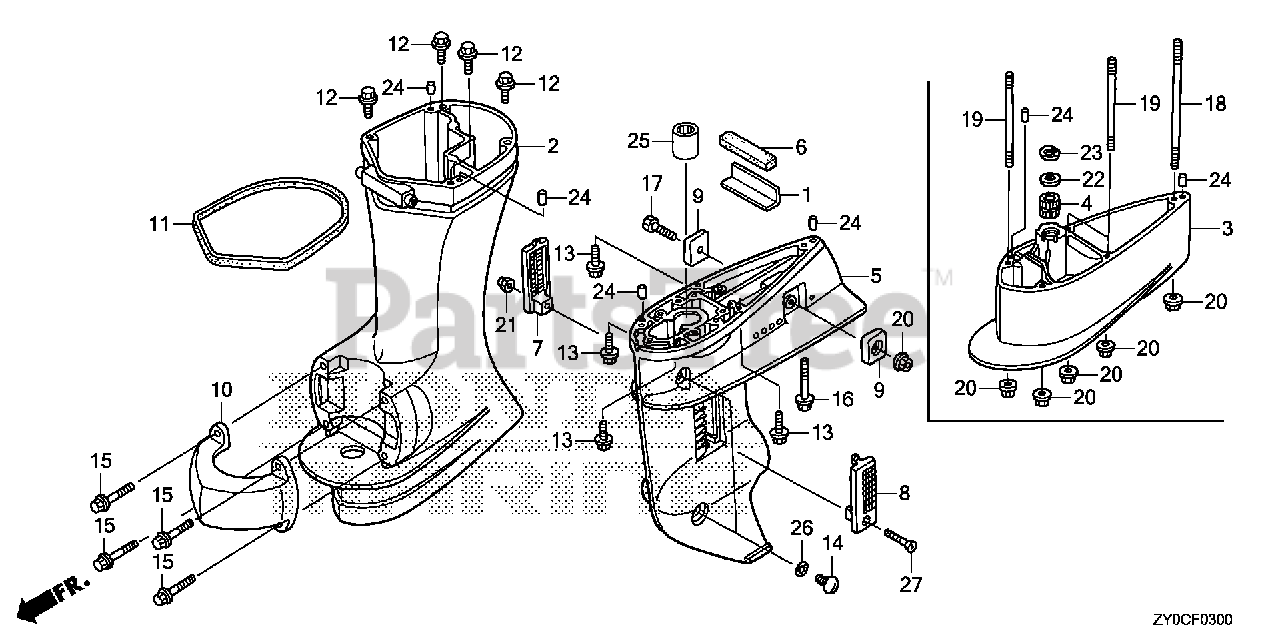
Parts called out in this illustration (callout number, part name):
1	PLATE, RUBBER SETTING
2	CASE, EXTENSION *NHB14M* (L) (AQUA MARINE SILVER METALLIC)
5	CASE, GEAR *NHB14M* (AQUA MARINE SILVER METALLIC)
6	GROMMET, GEAR CASE
7	SCREEN, R WATER
8	SCREEN, L. WATER
9	METAL, ANODE
10	HOUSING, MOUNTING (LOWER) *NHB14M* (AQUA MARINE SILVER METALLIC)
11	RUBBER, COVER (LOWER)
12	BOLT, FLANGE (8X35) Use from Frame SN 4800713.
13	BOLT, FLANGE (6X23) Use from Frame SN 4800343.
14	BOLT, OIL CHECK
15	BOLT, FLANGE (6X20) (ENGINE NO.)
16	BOLT, FLANGE (6X75)
17	BOLT, HEX. (6X25) Use up to Frame SN 4800342.
20	NUT, SELF-LOCK (6MM)
21	NUT, SELF-LOCK (5MM)
24	PIN, DOWEL (6X10)
25	BEARING, NEEDLE (15X22X20)
26	O-RING (6.9X1.45)
27	SCREW, OVAL (5X28)
